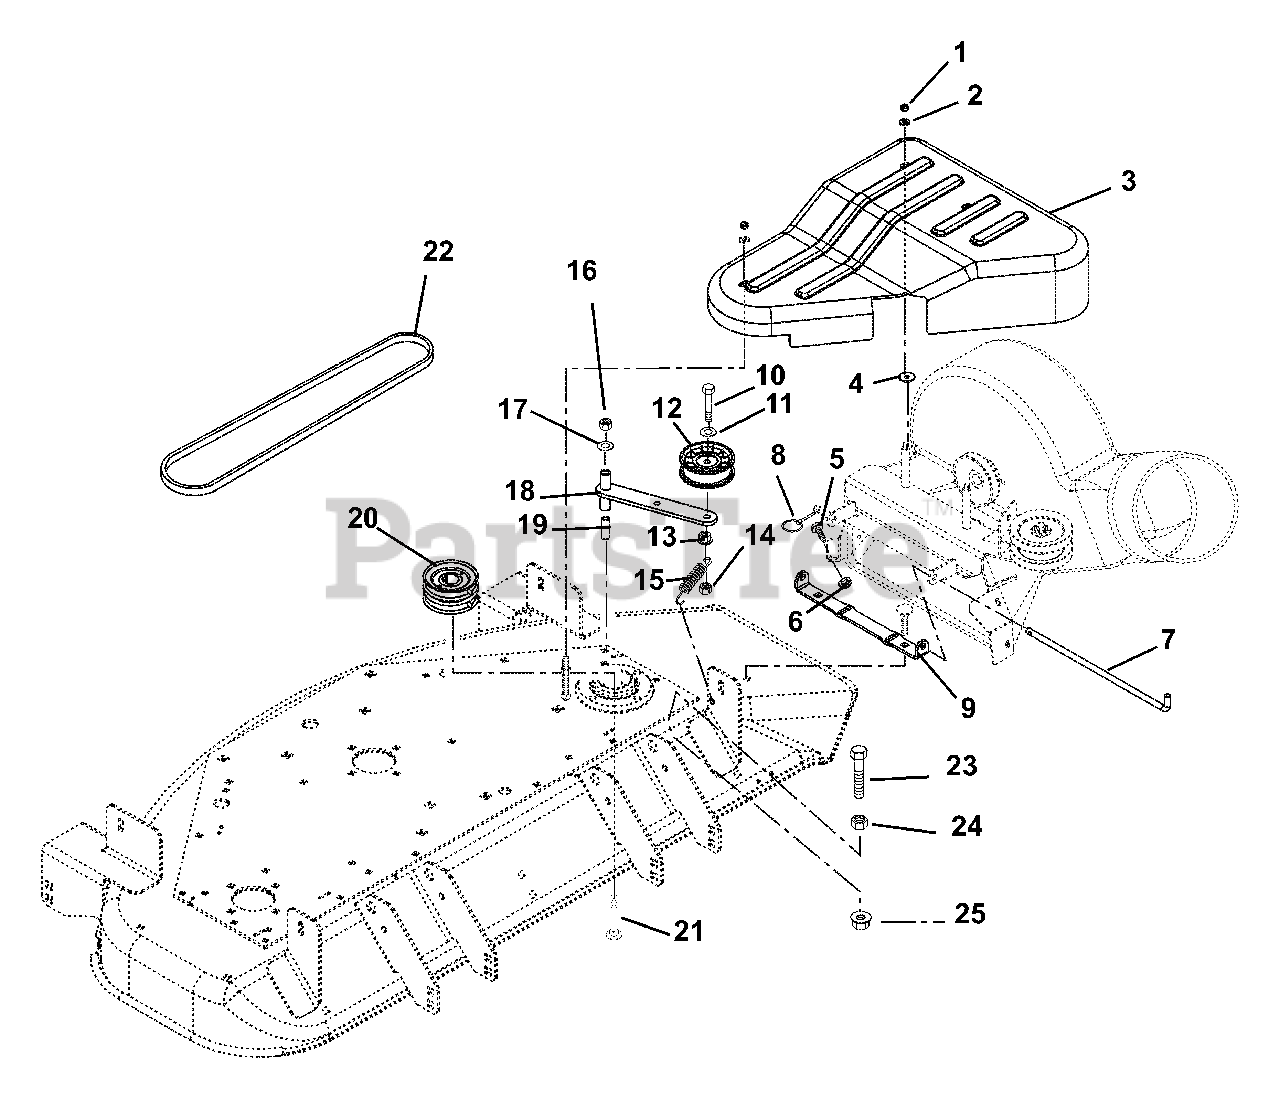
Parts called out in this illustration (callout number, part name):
1	@NUT-LK-NYL .250-20 YWZC
2	@WSHR-FL-STL.281X.62X.065 YWZC
3	COVER-BELT GUARD
4	WSHR-FL-STL .281X1.000X.063
5	@SCR-MCH 10-24X.50 HWH YWZC
6	@NUT-LK-NYL 10-24 W/INSRT YWZC
7	ROD-MOUNTING
8	PIN-KLIK 1.000X.188X1.25 YWZC
9	BRACKET, CHUTE PIVOT
10	@BLT-HEX .38-16X2.50 GR5 YWZC
11	@WSHR-FL-STL.438X1.00X.083 YWZ
12	IDLER FLANGED 3.50
13	@NUT-SPNLK-FLG .375-16 YWZC
14	@NUT-LK-NYL .38-16 YWZC
15	SG-TENS .069X.62X3.50 WLD20
16	@NUT-LK-NYL .312-18 YWZC
17	WSHR-FL-STL .328X1.0X.094 YWZC
18	BRACKET - TENSION ARM
19	SPACER .344 X .613 X 1.780
20	PULLEY-DOUBLE V, 3.50 X 1.004
21	BLT-RDHDSQSHNK.31-18X2.75G2YWZ
22	V-BELT, 4L-WRAPPED
23	@BLT-HEX .38-16X1.75 GR5 YWZC
24	@NUT-HEX .38-16 YWZC
25	@NUT-LK-TOP-FLG .38-16 YWZC
